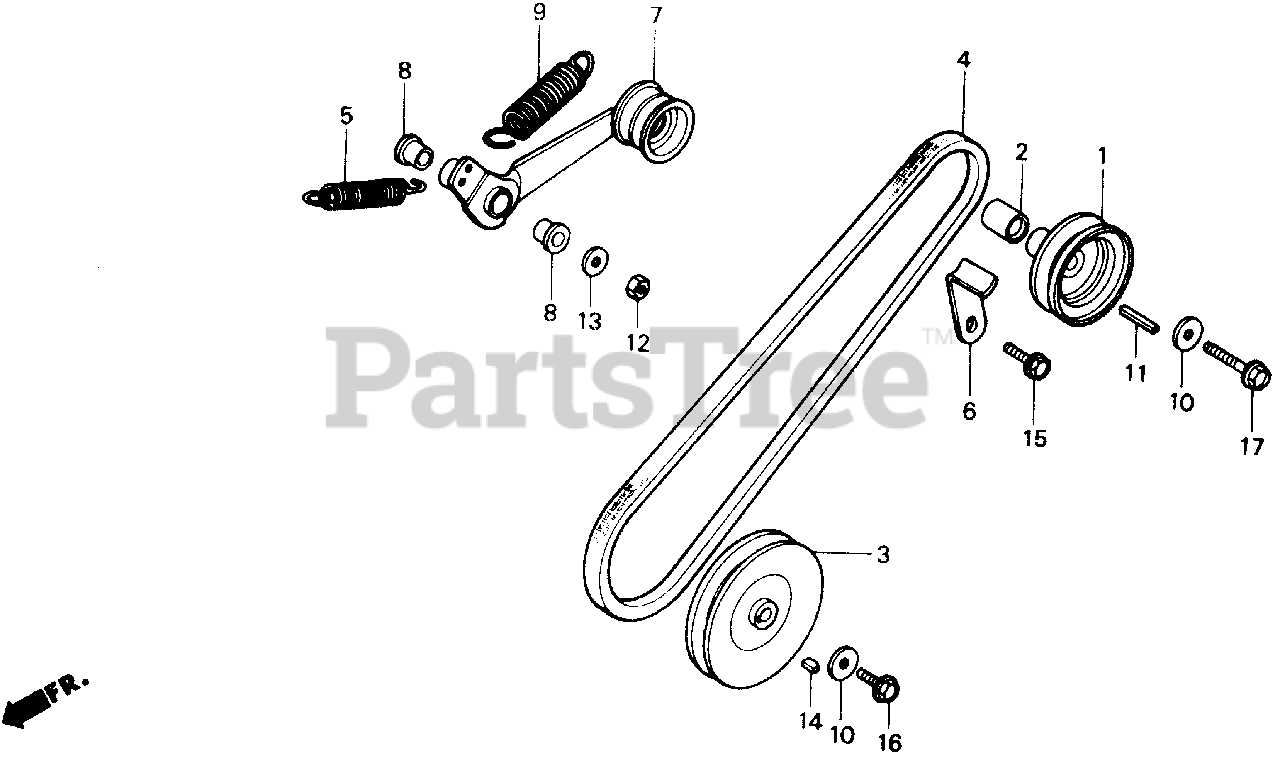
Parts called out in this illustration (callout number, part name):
1	PULLEY, DRIVEN (NOT AVAILABLE)
2	COLLAR, DRIVE PULLEY
3	PULLEY, DRIVEN (NOT AVAILABLE)
4	V-BELT (SB-38)
5	SPRING, TENSIONER ARM RETURN
6	STOPPER, BELT
7	ARM, TENSIONER
8	BUSH, TENSIONER ARM
9	SPRING, BELT TENSIONER
10	WASHER (8MM)
11	KEY (5X5X33)
12	NUT, HEX. (8MM)
13	WASHER, PLAIN (8MM)
14	KEY, WOODRUFF (16X12)
15	BOLT, FLANGE (8X12)
16	BOLT, FLANGE (8X16)
17	BOLT, FLANGE (8X32)
